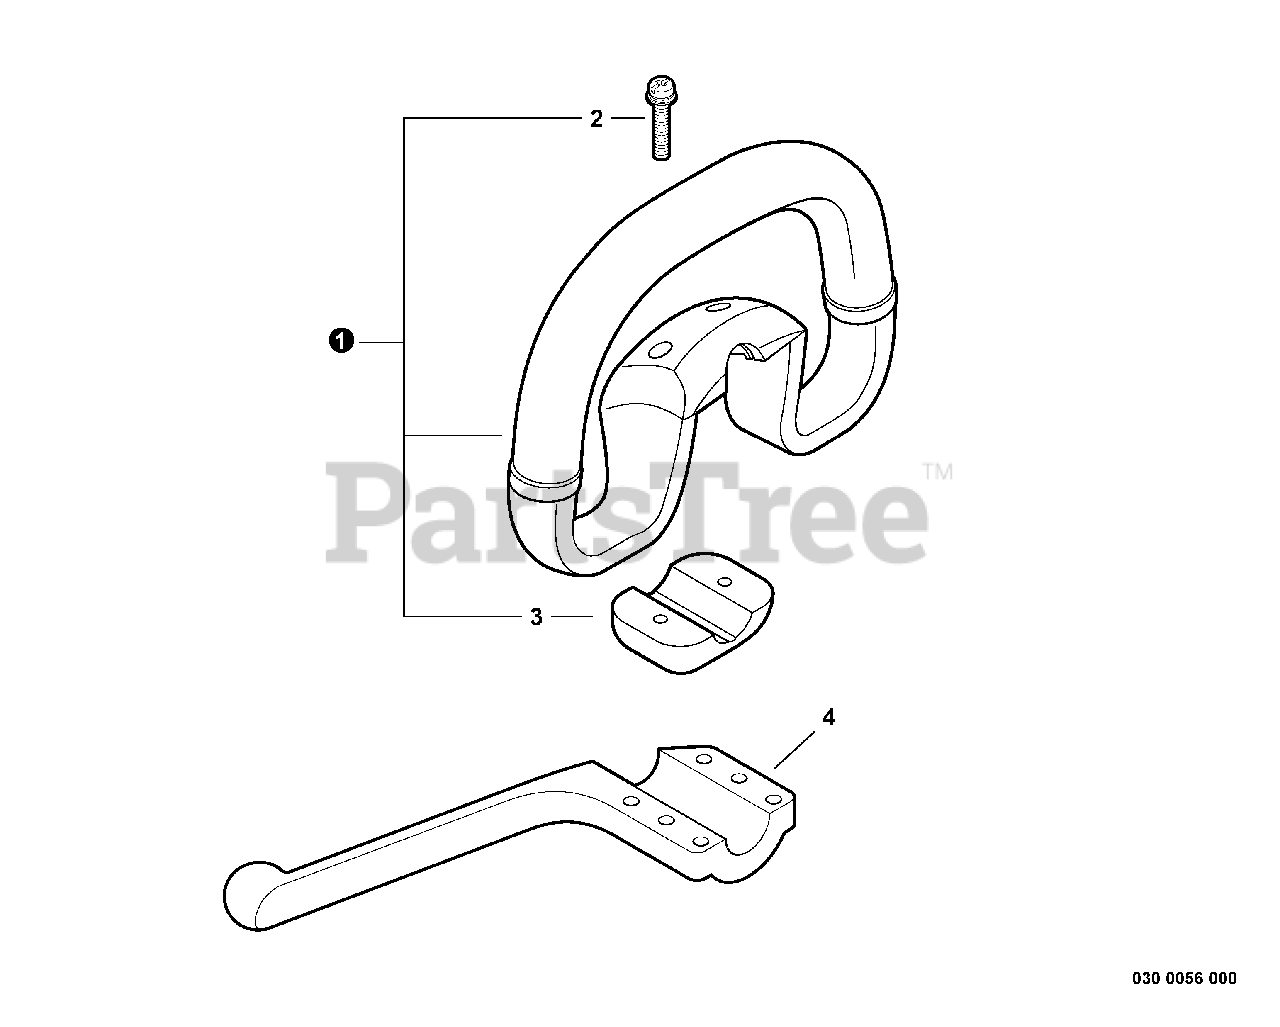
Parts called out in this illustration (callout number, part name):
1	HANDLE ASSY - SUPPORT
2	SCREW 5×40
3	BRACKET, HANDLE
4	BAR, BARRIER
